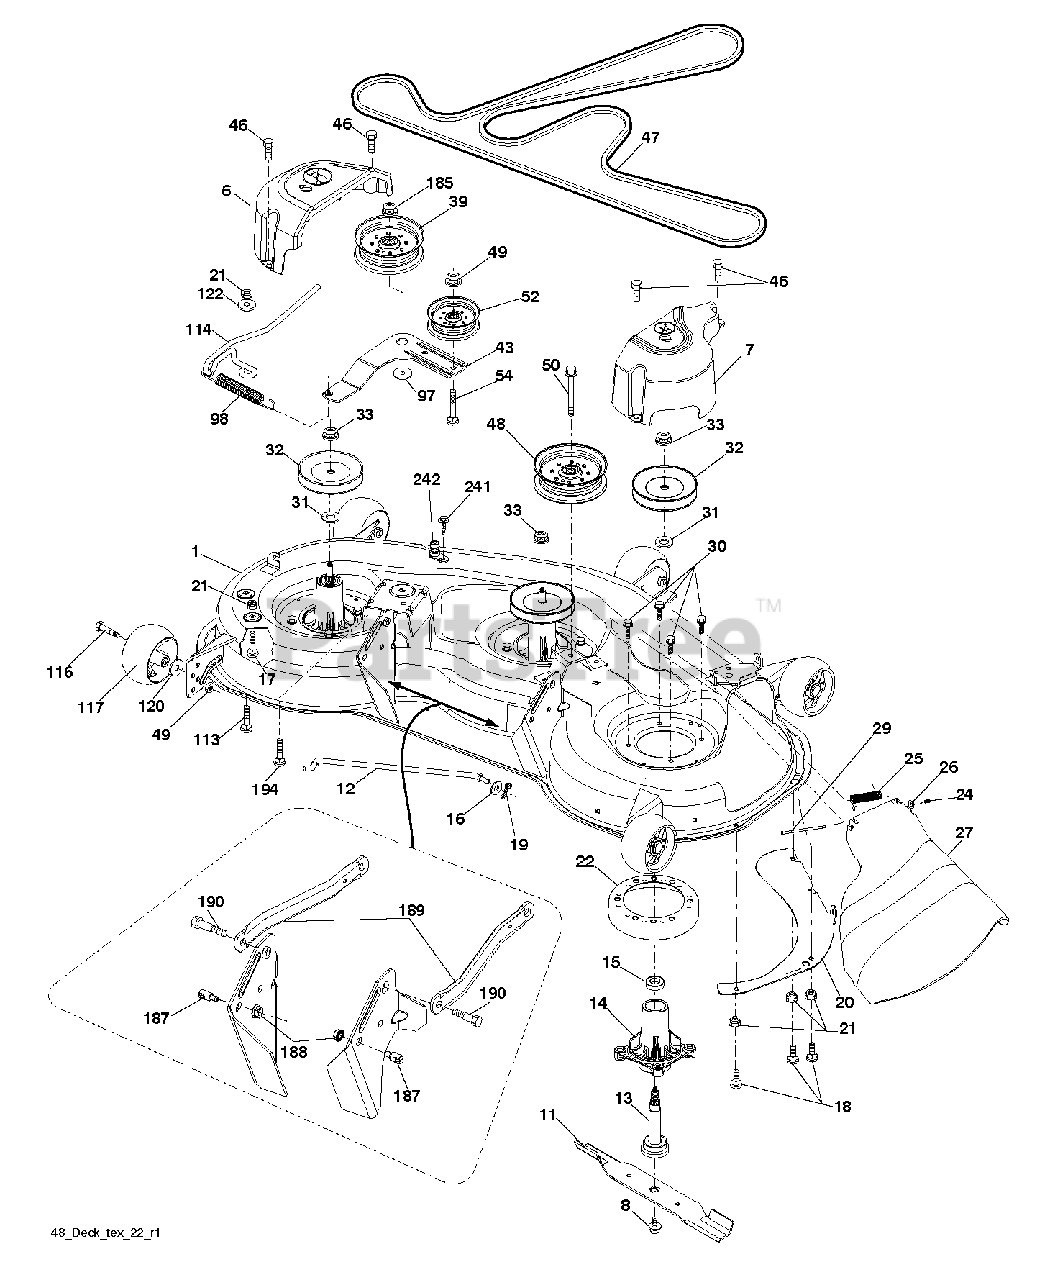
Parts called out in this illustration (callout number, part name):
1	DECK.PNT.WELDMENT.48"TEX.666
6	COVER.MANDREL.LH.48"
7	COVER.MANDREL.RH.48"
8	BOLT.WASHER.ASM.7/16-2
11	48" HI-LIFT BLADE
11	48" MULCH BLADE
12	ROD.ANTI.SWAY.48/54"K4
13	SHAFT ASM MANDREL
14	HOUSING MANDREL
15	BEARING
17	BOLT
18	BOLT
19	PIN.COTTER.5/16.BOW TI
20	BAFFLE, VORTEX MWR
22	STRIPPER, MWR ROUND
24	CAP-SLEEVE LT
25	SPRING, TORSION
26	NUT PUSH M
27	DEFLECTOR SUBS TO 532 180655
29	HINGE ROD
30	SCREW, WASHER HEAD
33	NUT.FLANGE.LOCK.TOP
39	PULLEY.IDLER.4.50/HUB SPECIAL
43	ARM.IDLER
46	SCREW 1/4-20X5/8
47	BELT.DRIVE.DECK
50	SCREW TT 3/8-16X2-1/4 UNC
52	PULLEY.IDLER.48"PRIMARY
98	SPRING.DRIVE.DECK.2006
113	BOLT CRT
114	ROD.TENSION.RELIEF.TEX
116	BOLT.SHOULDER.3/8-16X3-5/8
117	WHEEL. GUAGE RALLY
120	WASHER
122	BUSHING
185	NUT.LOCK.FLANGE.7/16
187	STUD.FASTNER.W/D.ANTI-
188	NUT LOCK HEX FLANGE 5/16-18
189	ARM.SUSPENSION.MOWER
190	BOLT.SHOULDER
194	BOLT.CARR.SQNK.7/16
242	PORT.WASHOUT
